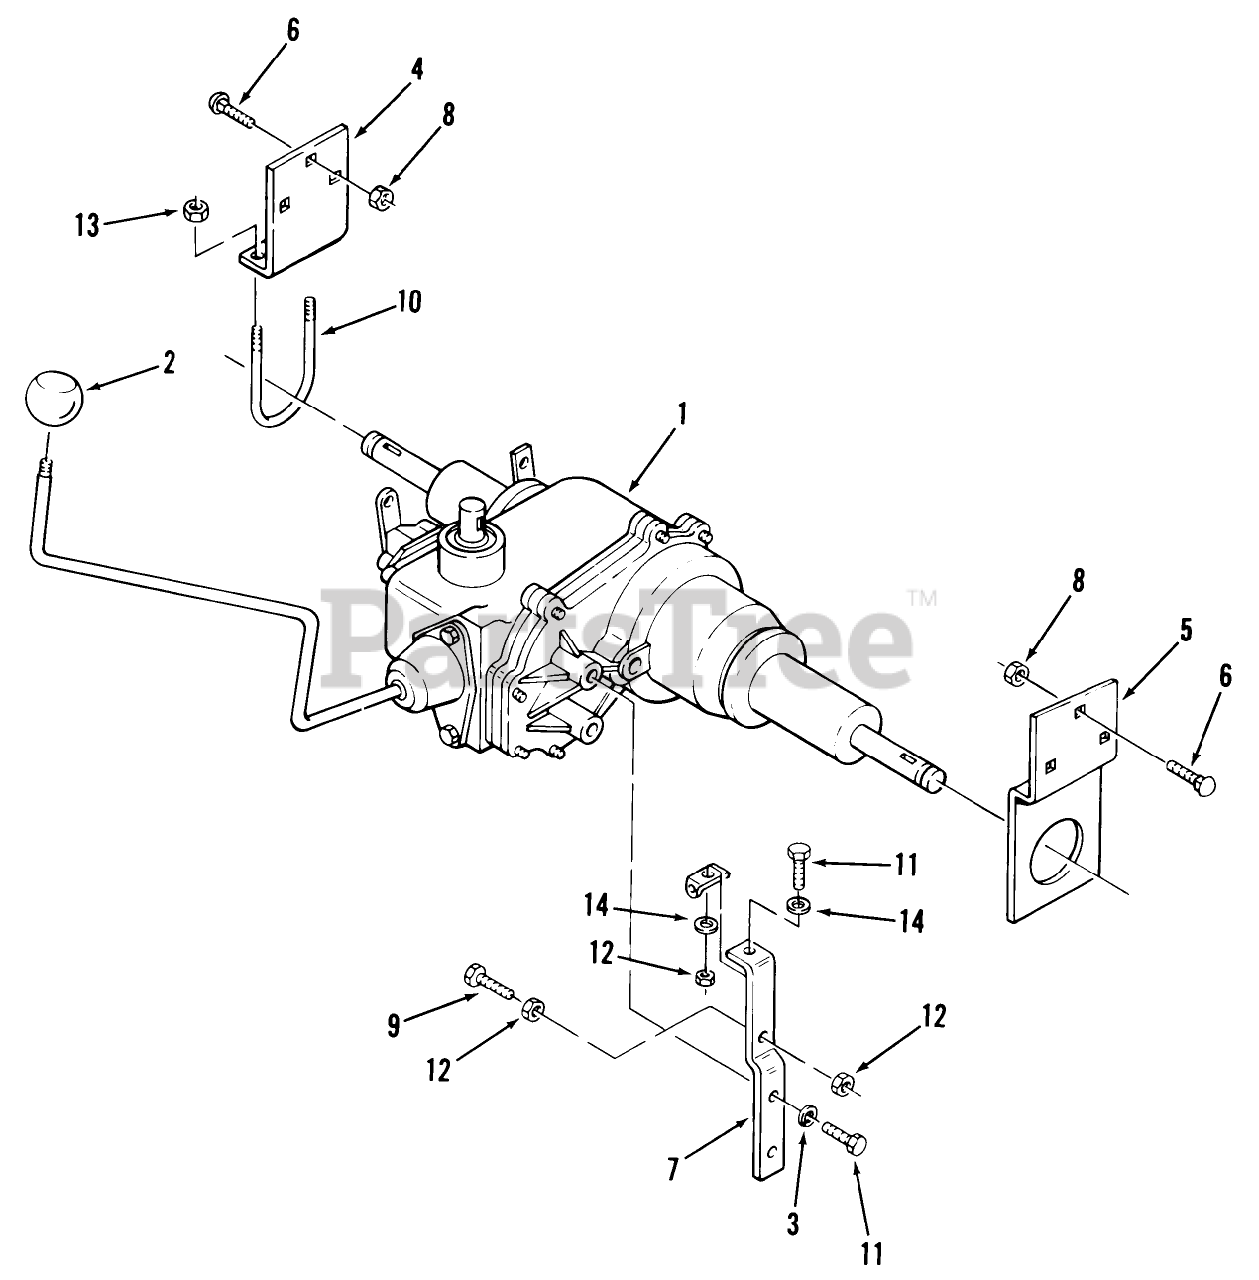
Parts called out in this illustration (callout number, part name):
1	ORDER FROM PEERLESS
2	SHIFT KNOB
6	CARRIAGE BOLT -4
14	WASHER 5/16 SAE
